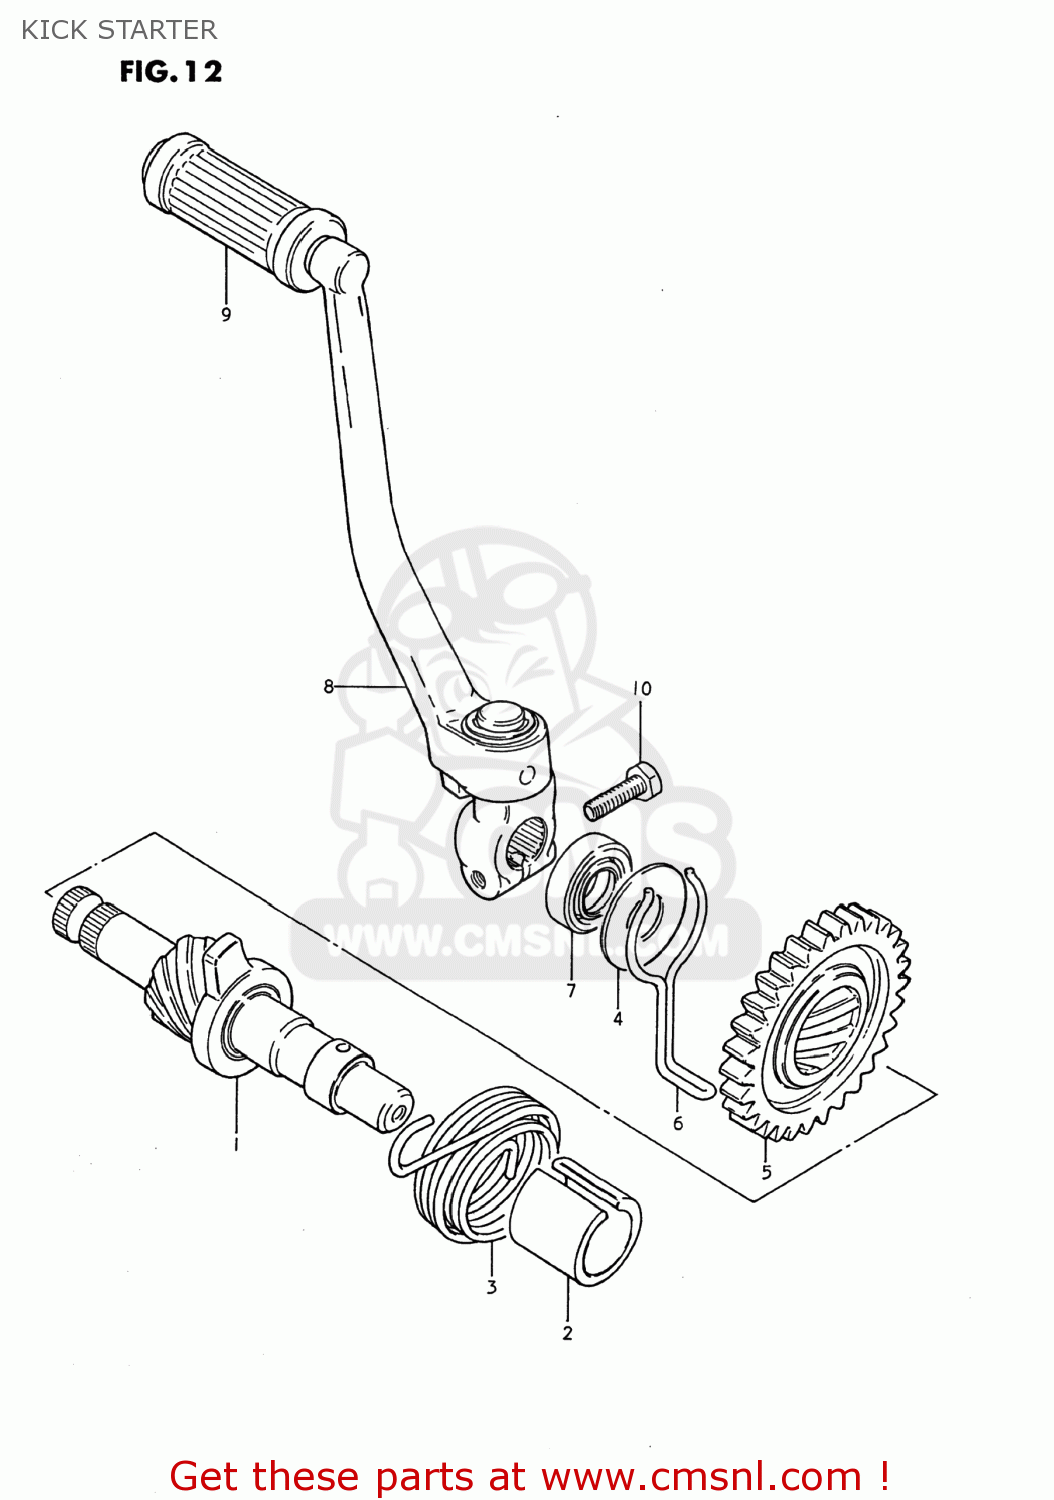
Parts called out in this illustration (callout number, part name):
1	SHAFT,KICK STARTER
2	GUIDE,KICK STARTER SFT SPRING
3	SPRING
4	WASHER
5	GEAR,KICK STARTER DRIVE(NT:30)
6	RETAINER,SNAP
7	SEAL,OIL(14X24X6)
8	LEVER ASSY,KICK STARTER
9	RUBBER,KICK STARTER PEDAL
10	BOLT
